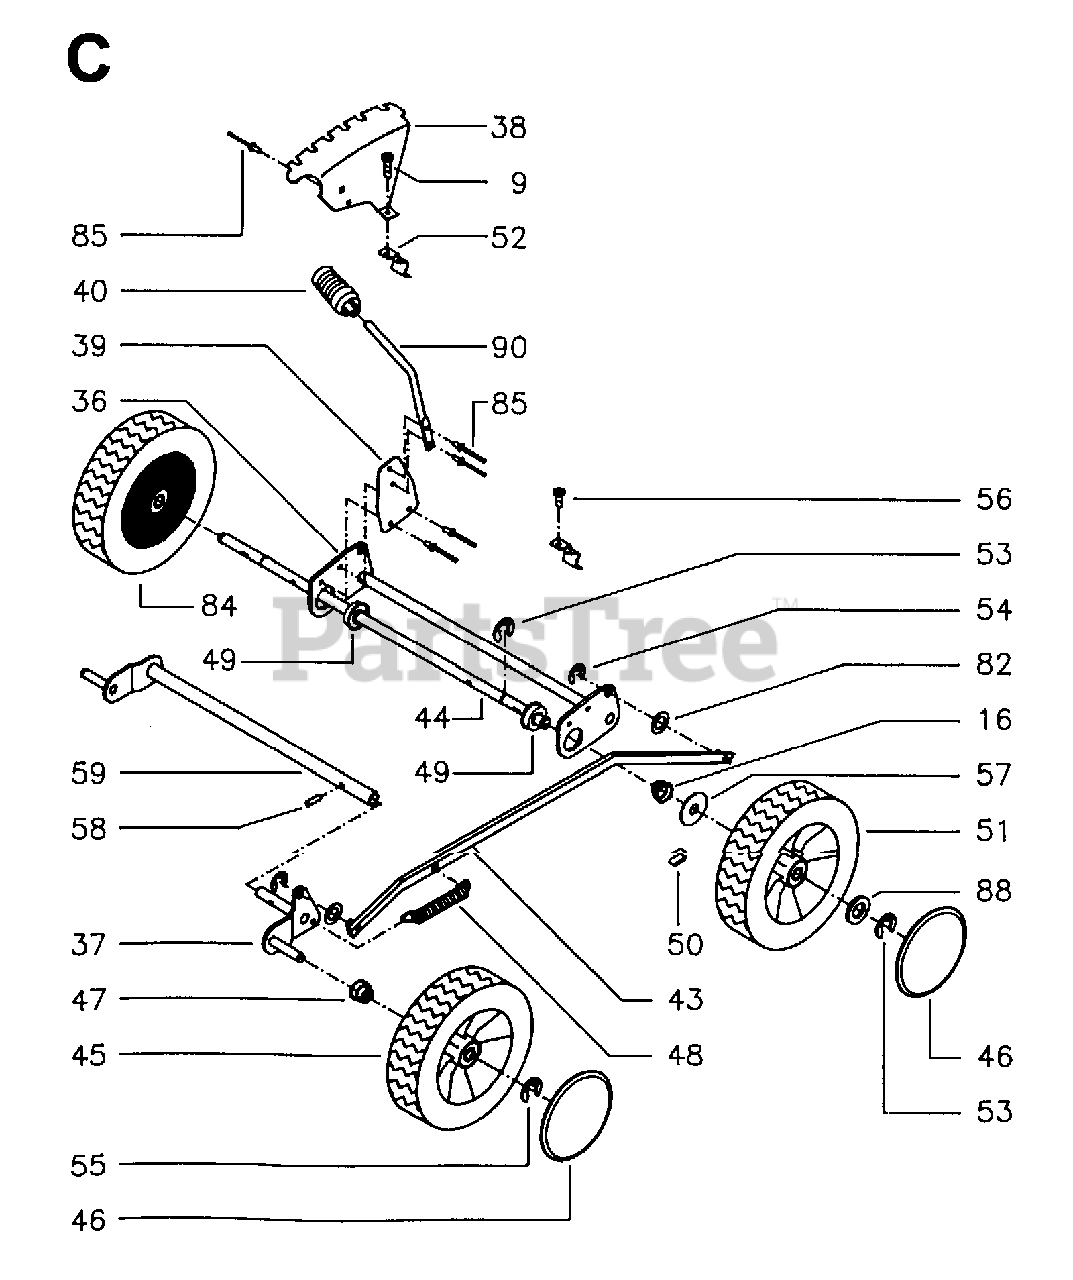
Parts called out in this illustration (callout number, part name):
47	CONE SPRING
50	CARRIER
53	SNAP RING
55	SNAP RING
